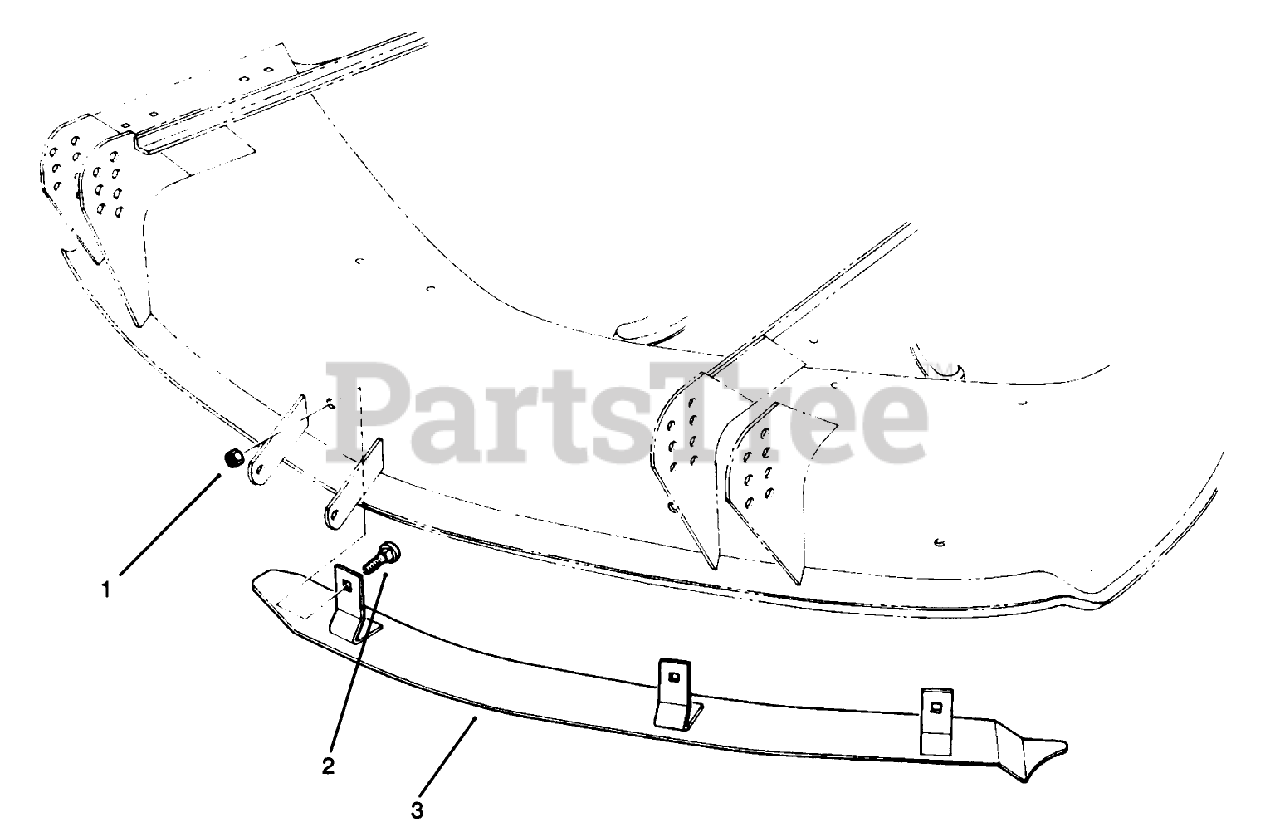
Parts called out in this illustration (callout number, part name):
1	NUT-LOCK, NI
2	SCREW-CARR
3	Baffle W.A.
